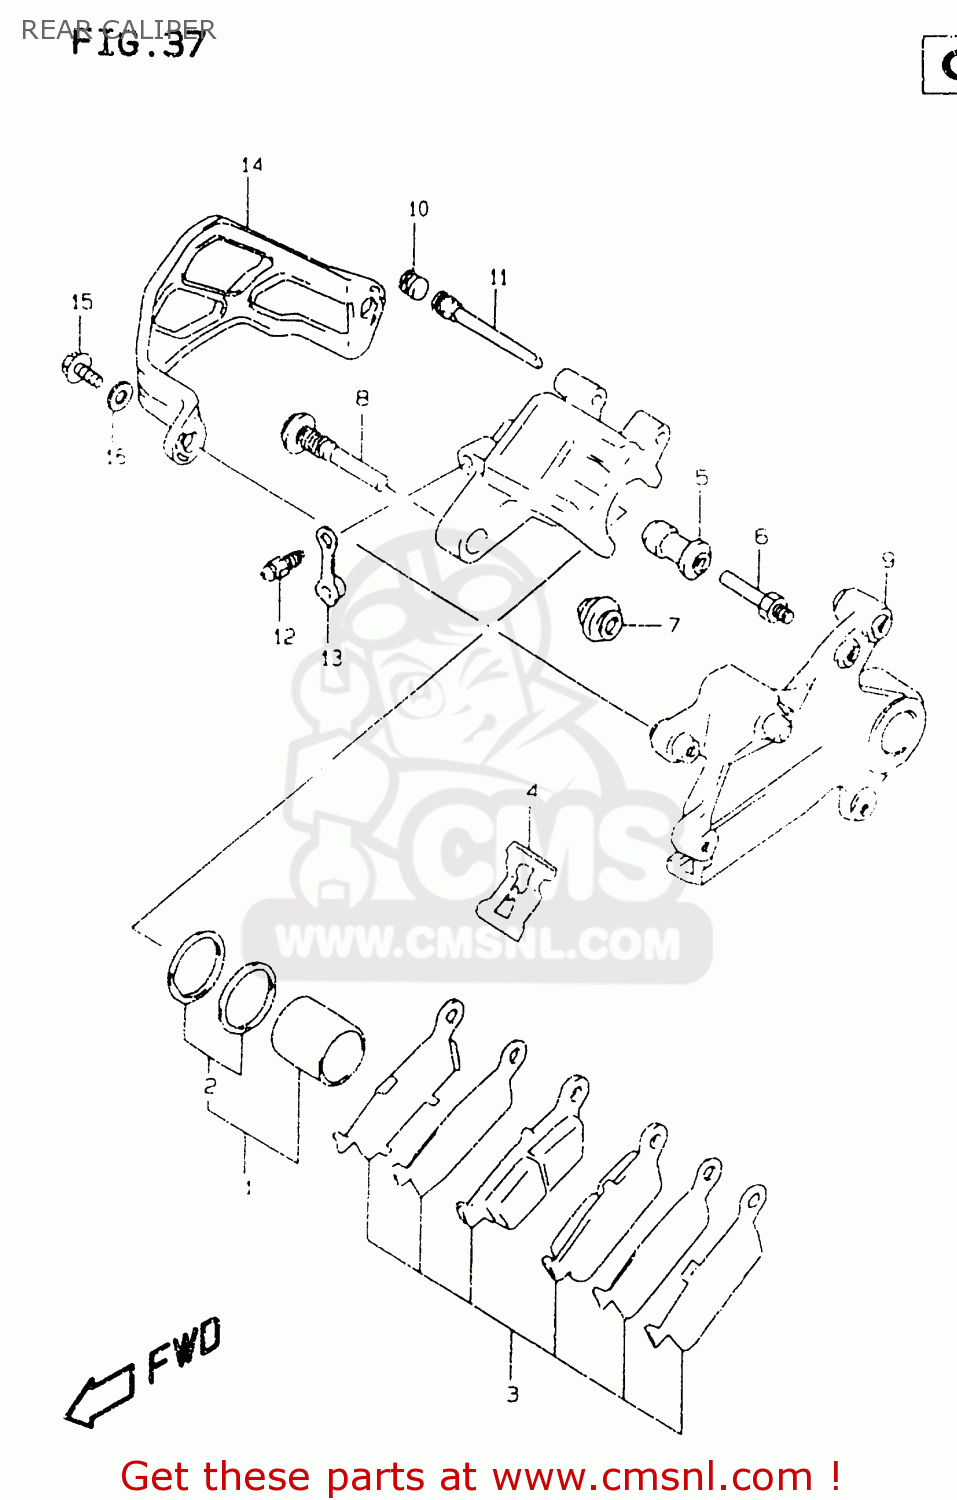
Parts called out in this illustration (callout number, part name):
1	PISTON SET
2	SEAL SET,PISTON
3	PAD & RETAINER SET
4	SPRING,PAD
5	BOOT
6	PIN,BOLT
7	BOOT
8	PIN,BOLT
9	BRACKET
10	PLUG,PIN
11	PIN,HANGER
12	BLEEDER
13	CAP,BLEEDER
14	GUARD,RR CALIPER
15	BOLT
16	WASHER
